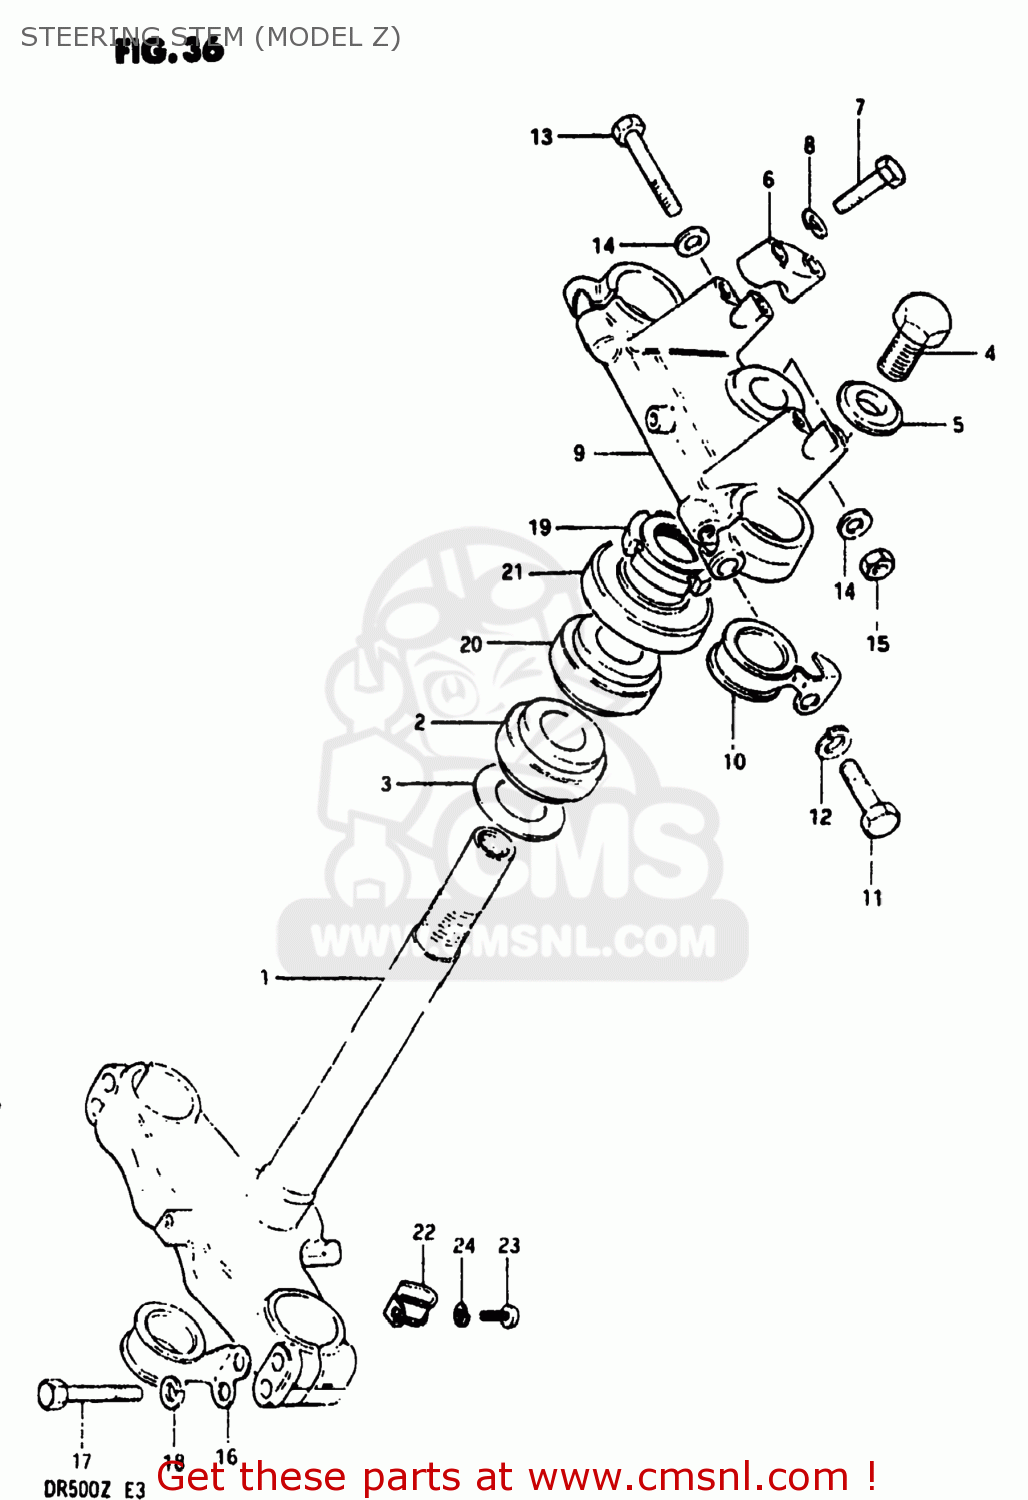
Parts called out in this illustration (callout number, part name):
1	STEM,STEERING
2	BEARING
3	WASHER,THRUST
4	BOLT
5	WASHER
6	HOLDER,HANDLEBAR
7	BOLT
8	LOCK WASHER
9	HEAD,STEERING STEM
10	GUIDE,CABLE
11	BOLT
12	LOCK WASHER
13	BOLT 8X50
14	WASHER
15	NUT
16	GUIDE,CABLE
17	BOLT 8X45
18	LOCK WASHER
19	NUT,STEERING STEM(25X44X10)
20	TAPER,ROLLER BEARING
21	DUST SEAL,STEERING UPR
22	CLIP,BRAKE CABLE
23	SCREW
24	LOCK WASHER
